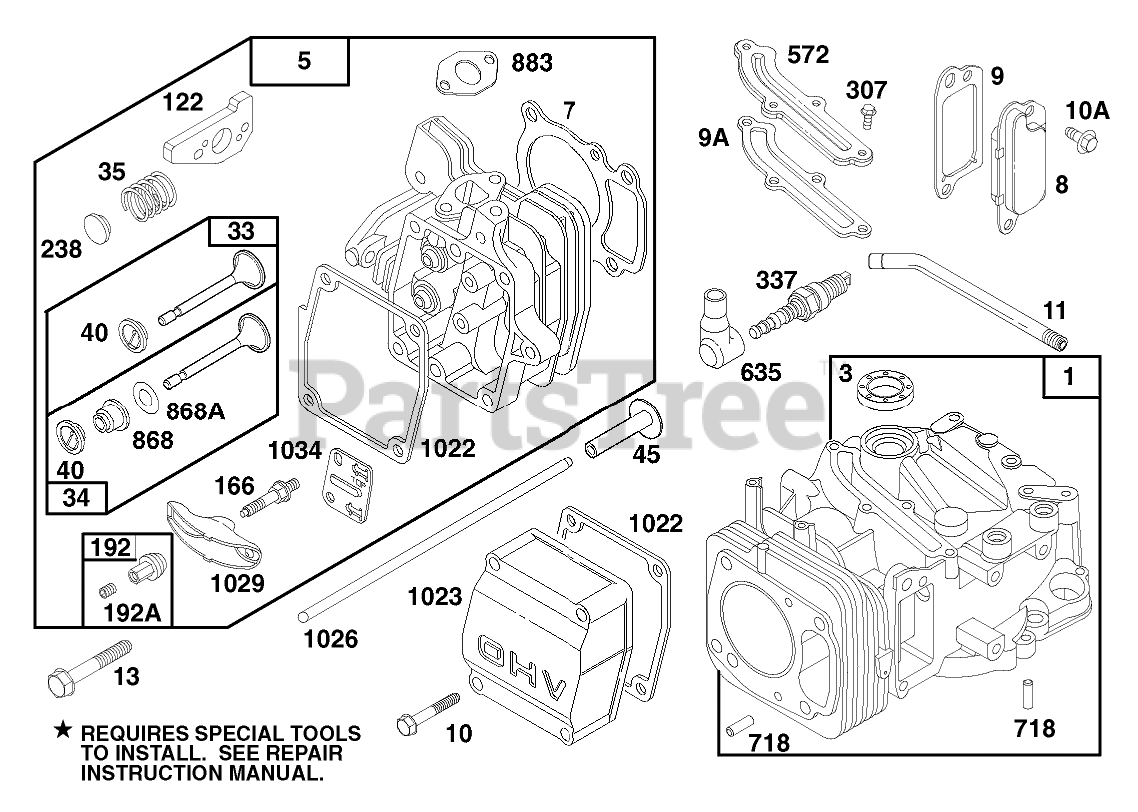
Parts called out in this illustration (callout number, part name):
1	CYLINDER ASSEMBLY
3	SEAL - OIL
5	CYLINDER HEAD
7	CYLINDER HEAD GASKET
8	Breather Assy
9	BREATHER GASKET
9A	GASKET-BREATHER
10	HEX HEAD SCREW
10A	HEX HEAD SCREW
11	TUBE - BREATHER
13	CYLINDER HEAD SCREW
33	EXHAUST VALVE
34	INTAKE VALVE
35	VALVE SPRING
40	SPRING RETAINER
45	VALVE TAPPET
122	ADAPTER ASSEMBLY
166	ROCKER ARM STUD
192	NUT - HEX SPECIAL
192A	SCREW SET
238	VALVE CAP
307	SCREW - SEM
337	PLUG-SPARK
572	BAFFLE - CYCLINDER
635	SPARK PLUG ELBOW
718	DOWEL - SLEEVE
868	SealAssy-Valve
868A	Seal-Valve
883	EXHAUST GASKET
1022	ROCKER COVER GASKET
1023	COVER - VALVE
1026	PUSH ROD
1029	ROCKER ARM
1034	PUSH ROD GUIDE
